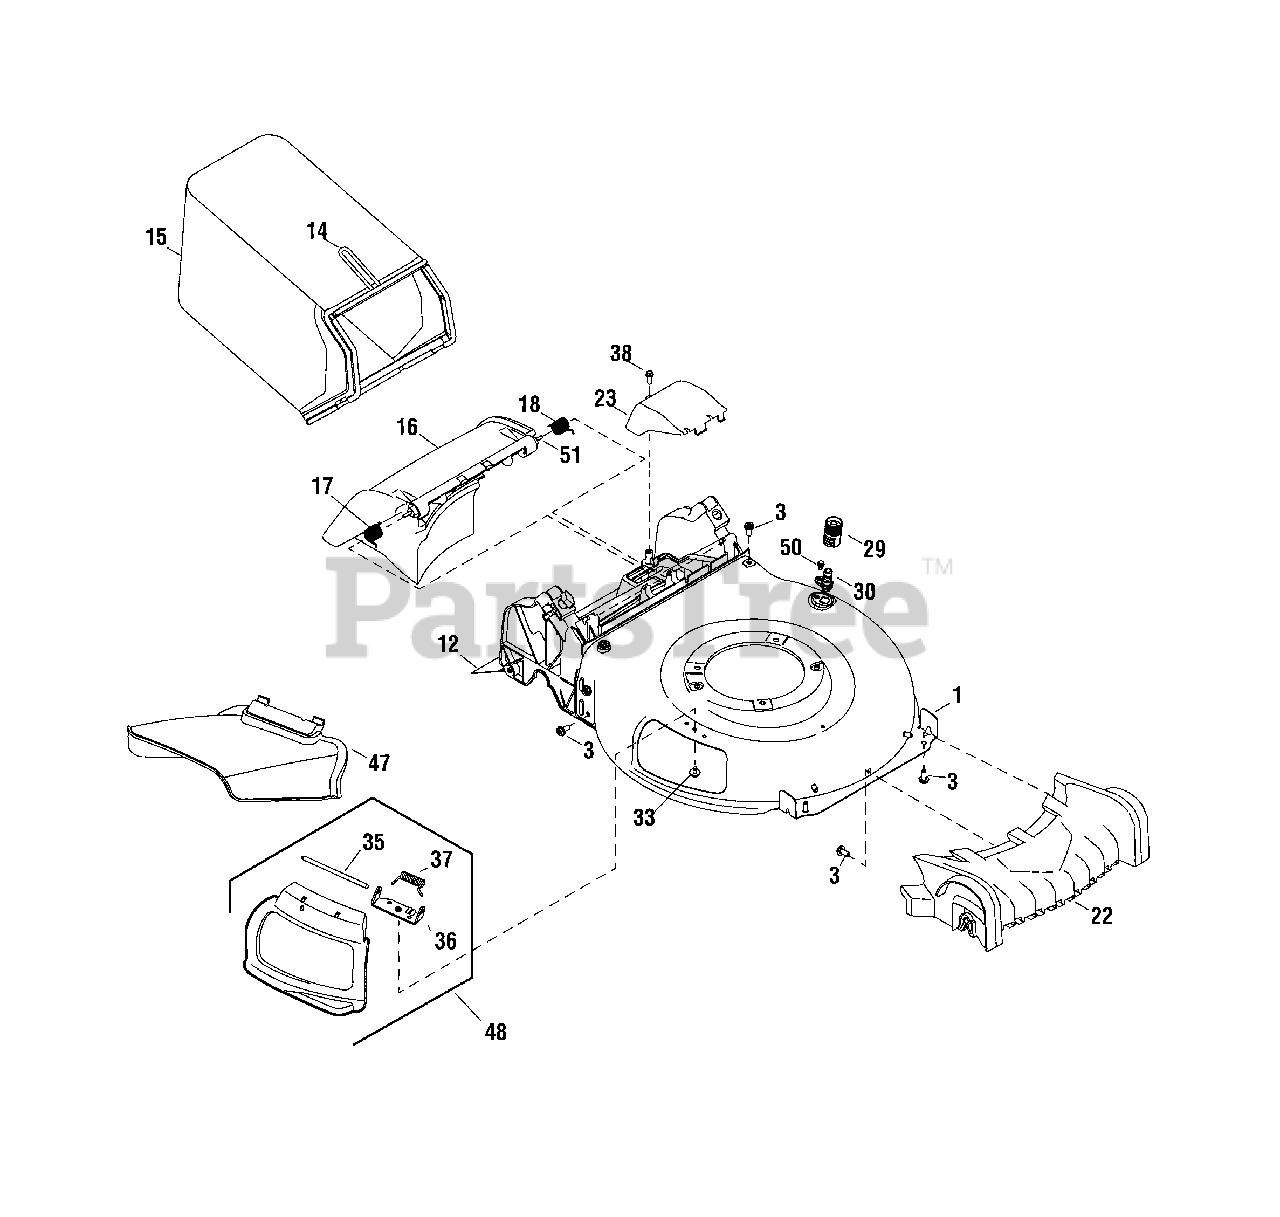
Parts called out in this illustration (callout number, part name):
3	SCREW, 5/16-14 x 3/4
12	SHIELD, Trailing
14	FRAME, Grass Bag
15	BAG, Grass
16	DOOR, Rear Discharge
17	SPRING, Torsion, RH
18	SPRING, Torsion, LH
22	COVER, Front
23	COVER, Transmission
29	ADAPTER, Water Nozzle
30	NOZZLE, Water
33	SCREW, 1/4-20 x 1/2
35	PIN, Hinge
36	BRACKET, Chute Deflector
37	SPRING, Torsion
38	SCREW, 1/4-15X3/4, Self-Tapping, BZ
47	CHUTE, Side Discharge
48	MULCH PLUG
50	BOLT, Shoulder, 1/2-20 x 1/2
51	ROD, Pivot
